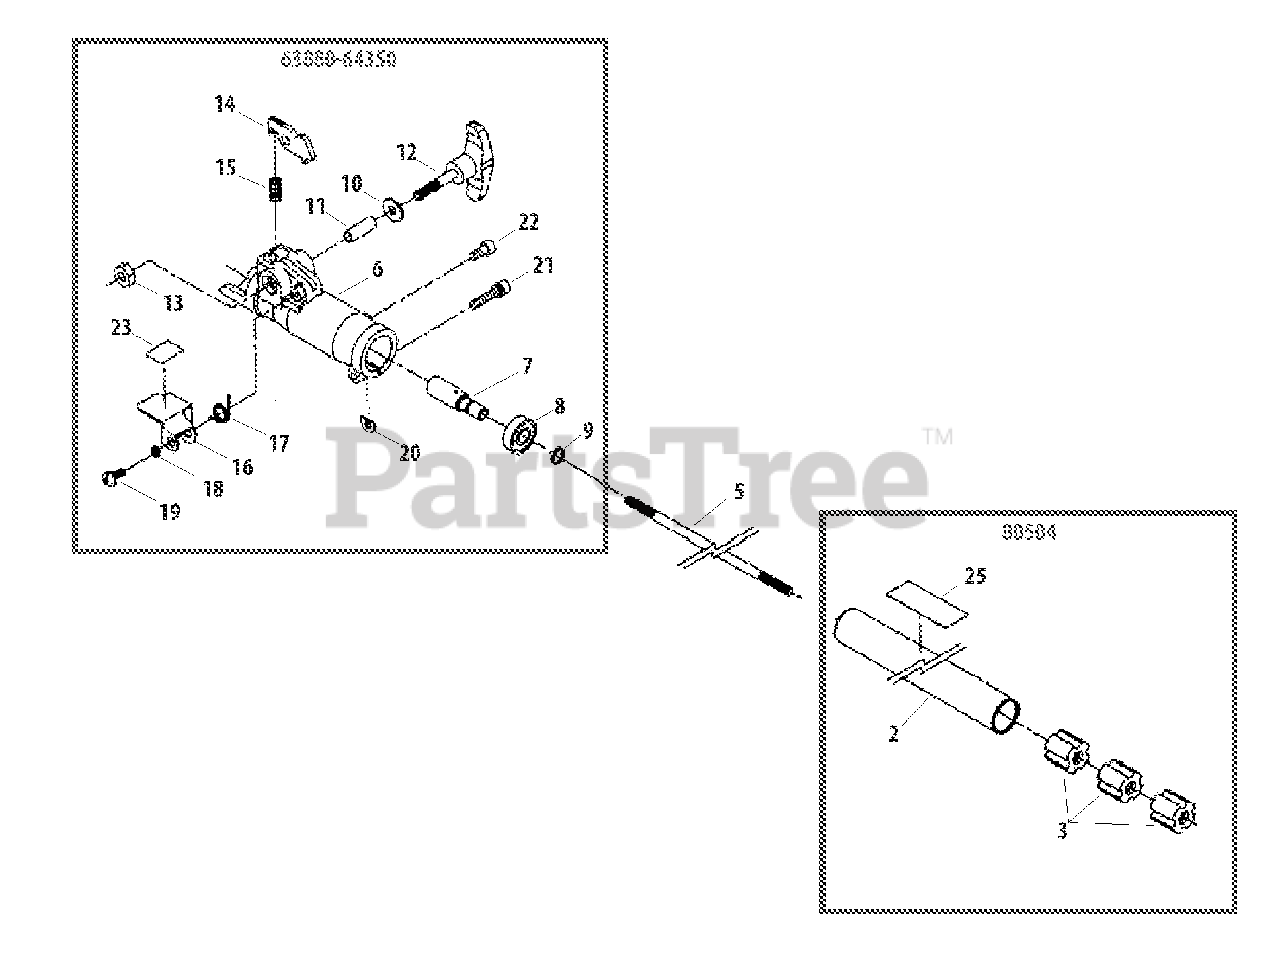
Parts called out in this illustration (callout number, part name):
2	PIPE, MAIN
3	BUSHING
5	PIPE, MAIN
6	COUPLER
7	CONNECTOR, SHAFT
8	BEARING, BALL - 609ZZ
9	RING, RETAINING
10	WASHER
11	COLLAR
12	KNOB
13	NUT
14	LEVER, LOCK
15	SPRING
16	COVER
17	SPRING
18	COLLAR
19	SCREW - 5X12
20	SHIM
21	SCREW - 5X20
22	SCREW - 5X12
23	LABEL - LATCH INSTRUCTION
25	LABEL - CAUTION
63880-64350	COUPLER ASSY
80504	MAIN PIPE ASSY
